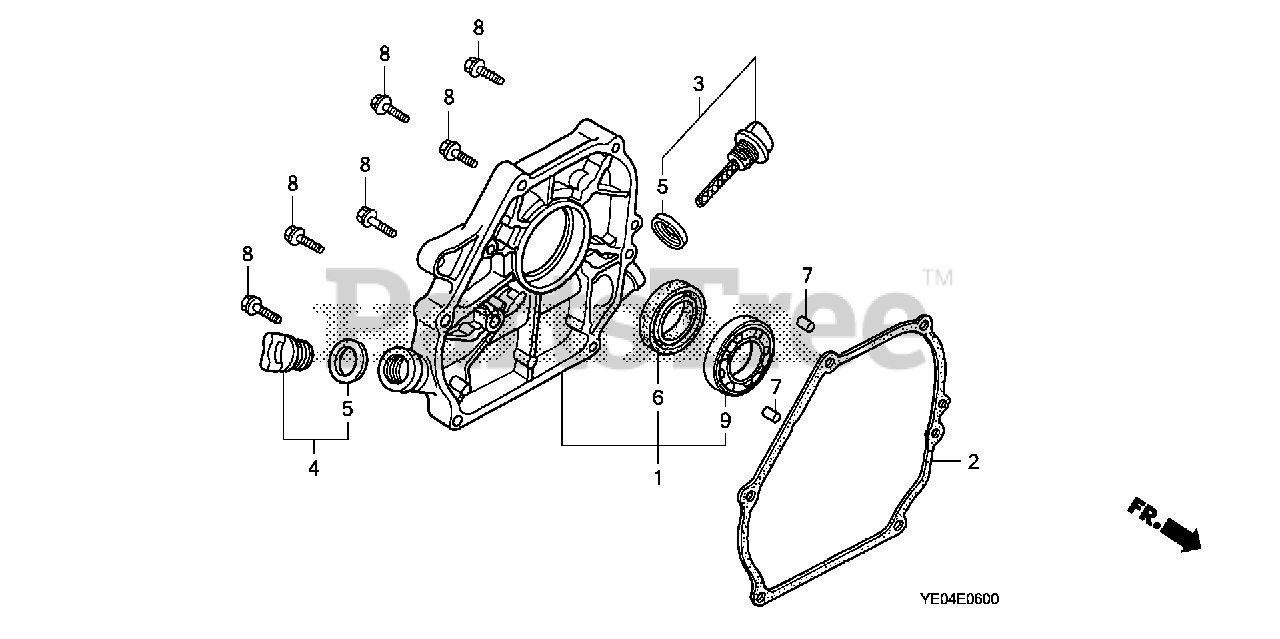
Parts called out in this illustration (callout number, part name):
1	COVER ASSY., CRANKCASE
2	GASKET, CASE COVER (NON-ASBESTOS)
3	CAP ASSY., OIL FILLER (GAUGE)(GRAY)
4	CAP ASSY., OIL FILLER (BLACK)
5	GASKET, OIL FILLER CAP
6	OIL SEAL (25X41X6) (NOK)
7	PIN, DOWEL (8X14)
8	BOLT, FLANGE (8X32)
9	BEARING, RADIAL BALL (6205)
